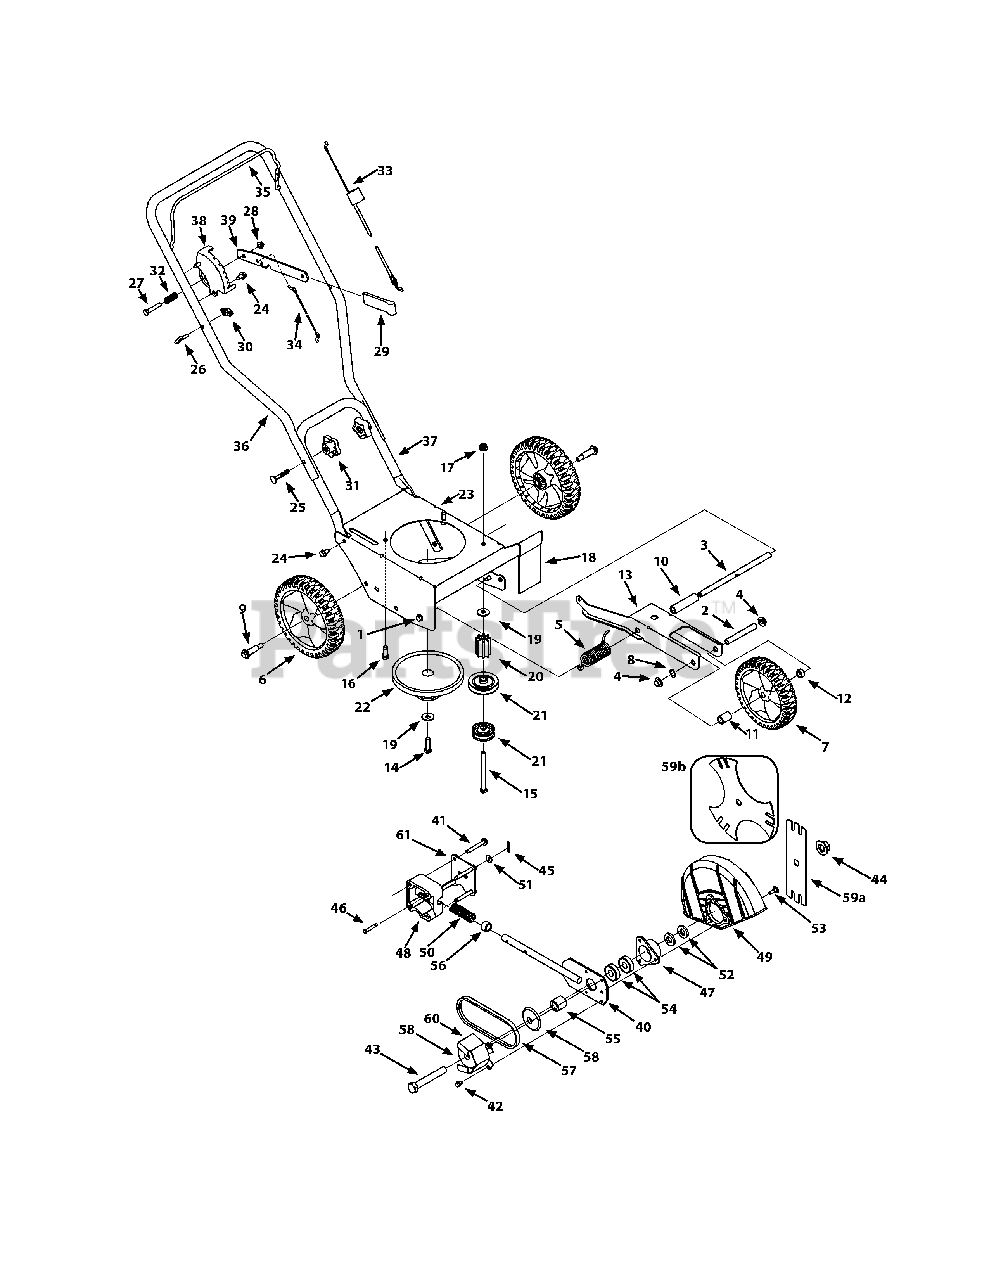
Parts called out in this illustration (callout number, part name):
1	Hex Head Screw 3/8-16
2	Axle .50 x 3.8
3	Axle .50 x 9.25
4	Push Cap 1/2" rod
5	Torsion Spring
6	Wheel 8x1.8
7	Wheel 7x1.8
8	Wave Washer
9	Shoulder Screw, 3/8-16
10	Spacer
11	Spacer, .525 x .775 x .1125
12	Spacer, .525 x .775 x .3125
14	Screw 3/8-24
15	Screw 3/8-16
16	Screw, 3/8-16
17	Flange Lock Nut, 3/8-16
18	Debris Guard
19	Bell Washer, .396 x 1.140
20	Pulley Mount Spacer
21	Flat Idler Pulley, 2.5 OD
22	Combination Flywheel Pulley
23	Frame
24	Hex Screw, 5/16-12
25	Carriage Bolt, 5/16-18
26	Rope Guide (Eye Bolt)
27	Hex Screw, 5/16-18
28	Lock Flange Nut, 5/16-18
30	Wing Nut
31	Hand Knob
32	Compression Spring
33	Control Cable
34	Wheel Adjustment Cable
35	Blade Control
36	Upper Handle
37	Lower Handle
39	Depth Index Lever
40	Blade Plate Assembly
41	Hex Screw, 5/16-18
42	Self-tapping Screw, 1/4-20
43	Hex Screw, 5/8-18
44	Flange Nut, 5/8-18
45	Cotter Pin
46	Clevis Pin
47	Bearing Cup
48	Bearing Block
49	Blade Guard
50	Compression Spring
51	Flat Washer, .260 x.72
52	Flat Washer .635x1.24x.181
53	Shoulder Screw
54	Bearing, .625 ID x 1.57 OD
55	Spacer, .63 x 1.12 x 1.06
56	Spacer, .64 x.88 x .50
58	Sheave
60	Belt Guard
61	Cover Plate
62	Flat Washer, .385 x 1 x .135
63	Wheel, 8" x 1.75, Ball Bearing
64	Wheel, 7" x 1.75, Ball Bearing
65	Spacer, .505 x .88 x .44
66	Flat Washer, .53 x .93 x .050
67	Tri-Star Blade
